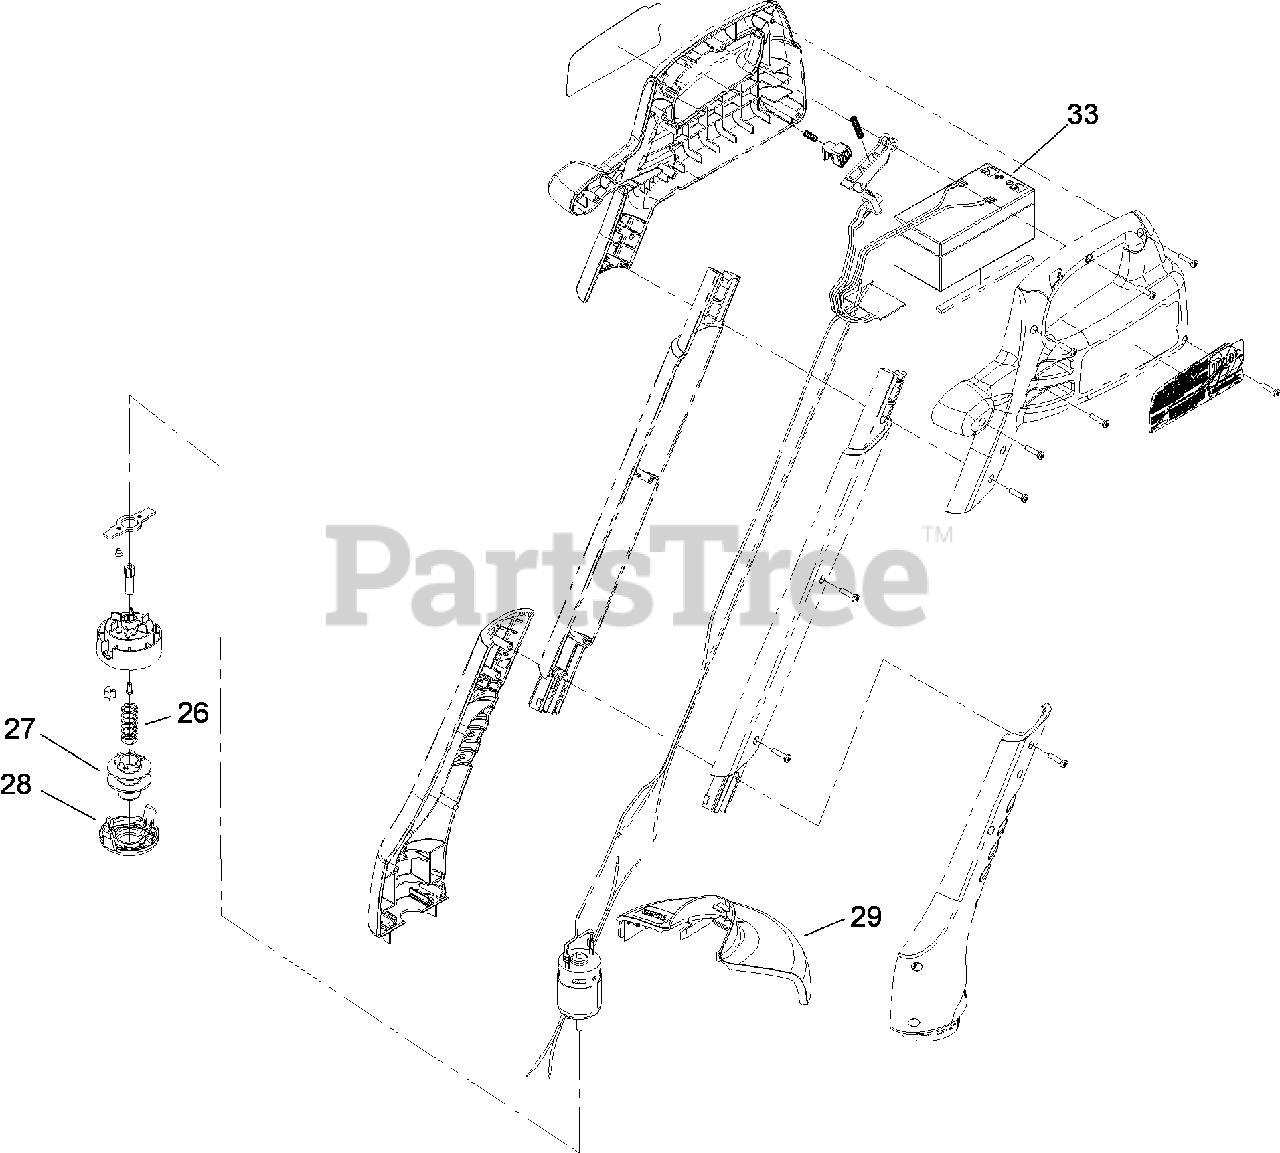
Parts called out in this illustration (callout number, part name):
26	SPRING-COMPRESSION
27	SPOOL ASM
28	CAP-SPOOL, 7 INCH
29	8 INCH SHIELD ASM
33	BATTERY ASM
